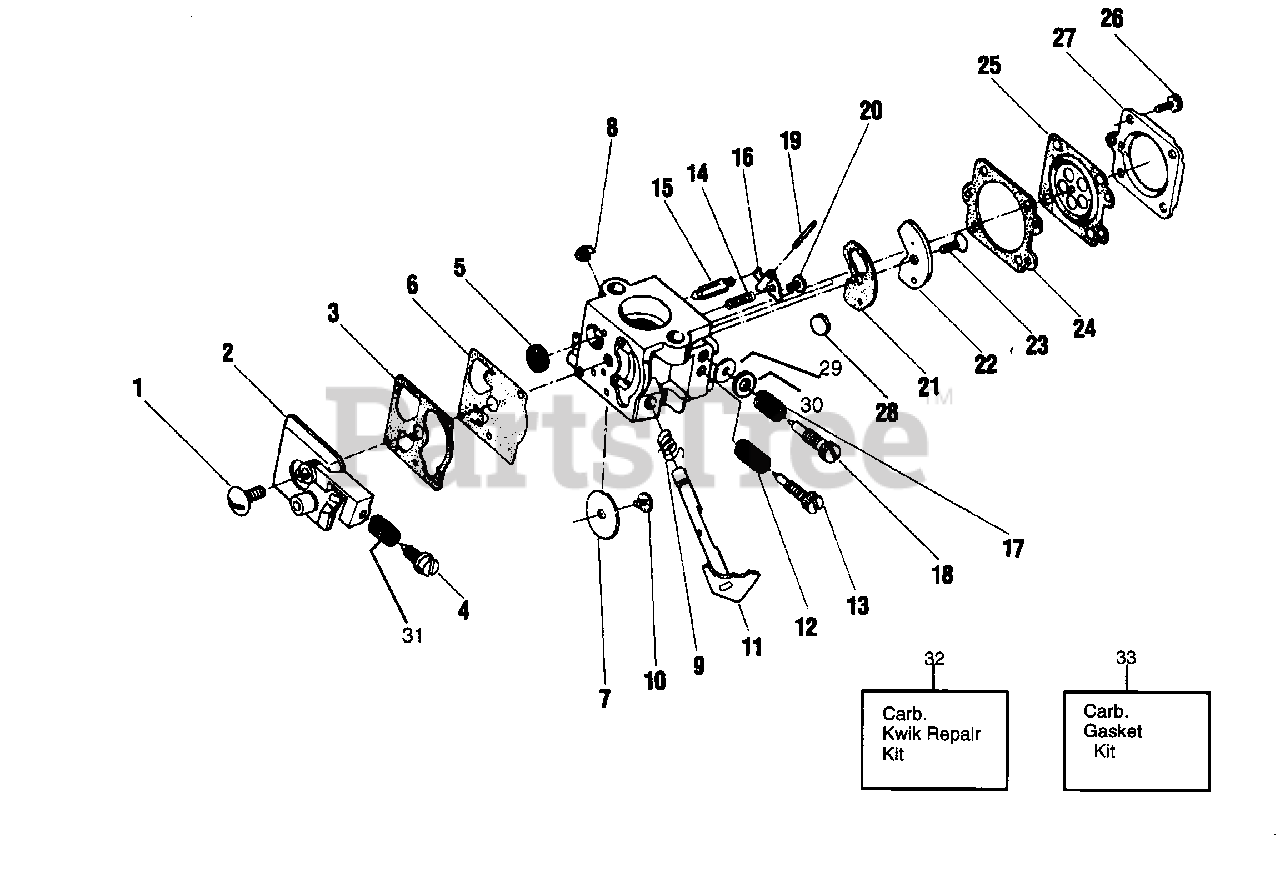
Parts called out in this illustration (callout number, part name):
1	Screw-Pump Cover
2	Pump Cover Ass'y. (Inc. #4)
3	Gasket-Pump
4	WA-149 & WT-63
5	Screen-Inlet
6	Diaphragm-Pump
7	WT-63 & WA-198
8	Clip-Throttle Shaft
9	Spring-Throttle Return
10	Screw-Throttle Valve
11	Shaft Ass'y.-Throttle
12	Spring-Idle Needle-WA-149
13	Needle-Idle-WA-149
14	Spring-Metering Lever
15	Valve-Inlet Needle
16	Lever-Metering
17	WT-63
17	WA-198
18	WA-149
19	Pin-Metering Lever
20	Screw-Metering Lever Pin
21	WA-149
23	Screw-Circuit Plate-WA-149 & WA-198
24	Gasket-Metering Diaphragm
25	Diaphragm Ass'y.-Metering
26	WT-63 & WA-198
27	WT-63 & WA-198
28	Plug-5/16" Dia. Welch WT-63 Only
29	"O" Ring Mixture
30	Mixture Washer
31	Spring-Idle Speed
33	WA-149 & WT-63
